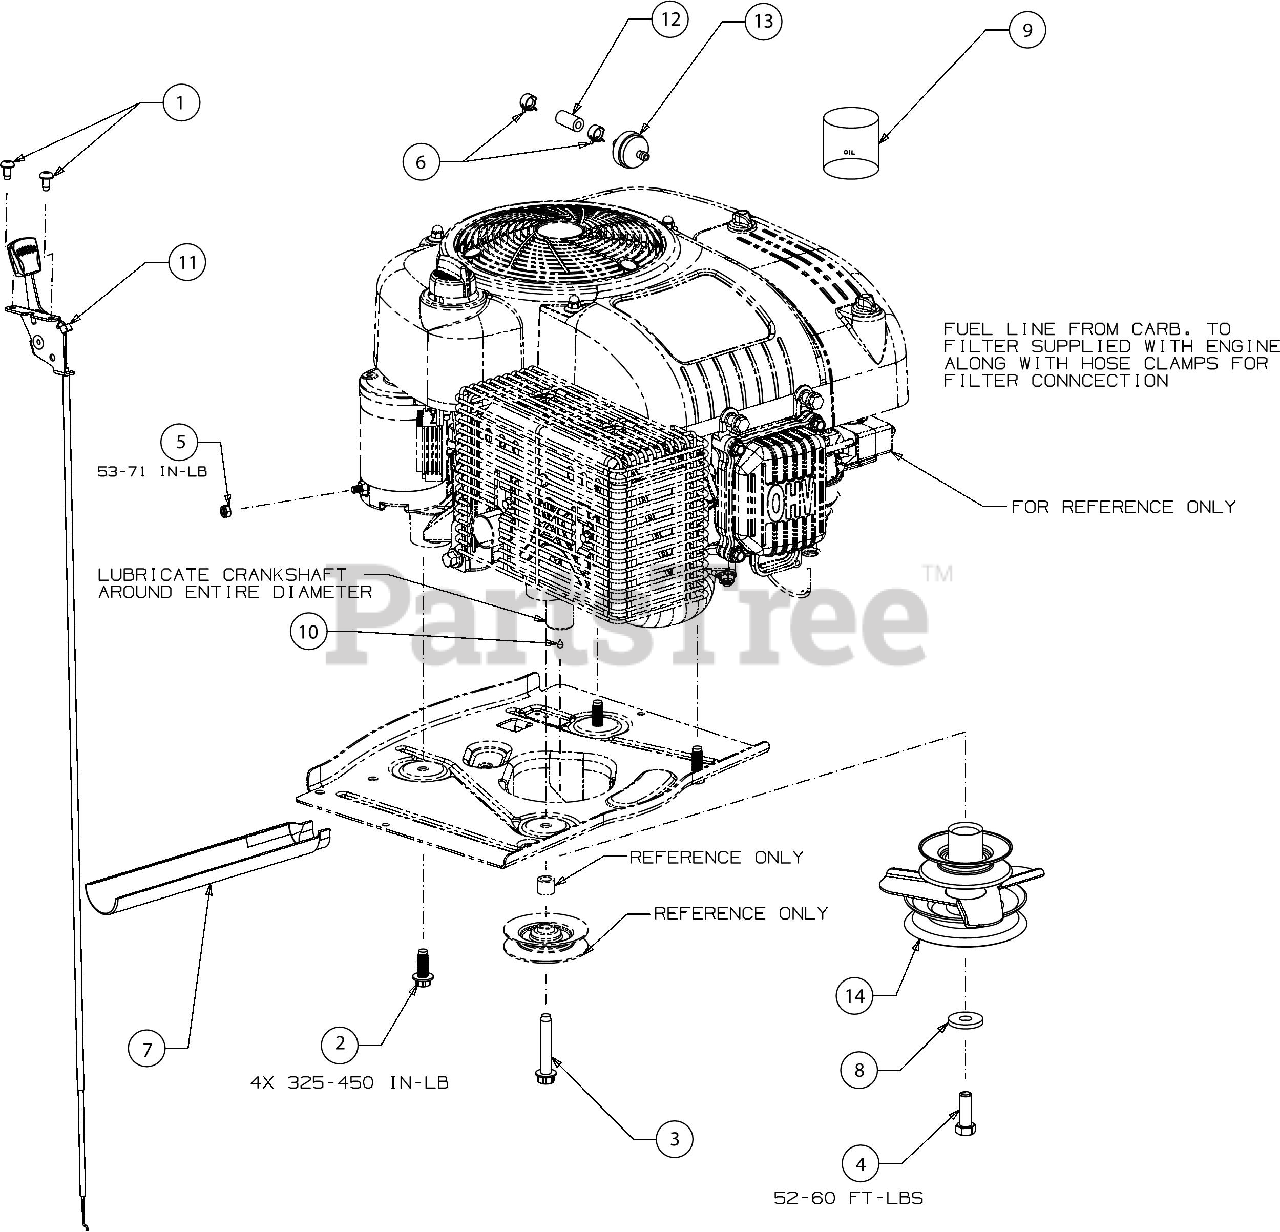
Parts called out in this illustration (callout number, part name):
1	SCREW 1/4-20 x .500
2	SCREW 3/8-16 x 1
3	SCREW 3/8-16 x 2.250
4	SCREW 7/16-20 x 1.250 GR5
5	HEX NUT
6	HOSE CLAMP 1/20
7	OIL DRAIN SLEEVE
8	FLAT WASHER .445 x 1.248 x .170
11	THROTTLE CABLE 31 x 1.1"
12	FUEL HOSE LOW PERMEATION
13	FUEL FILTER
14	ENGINE PULLEY
